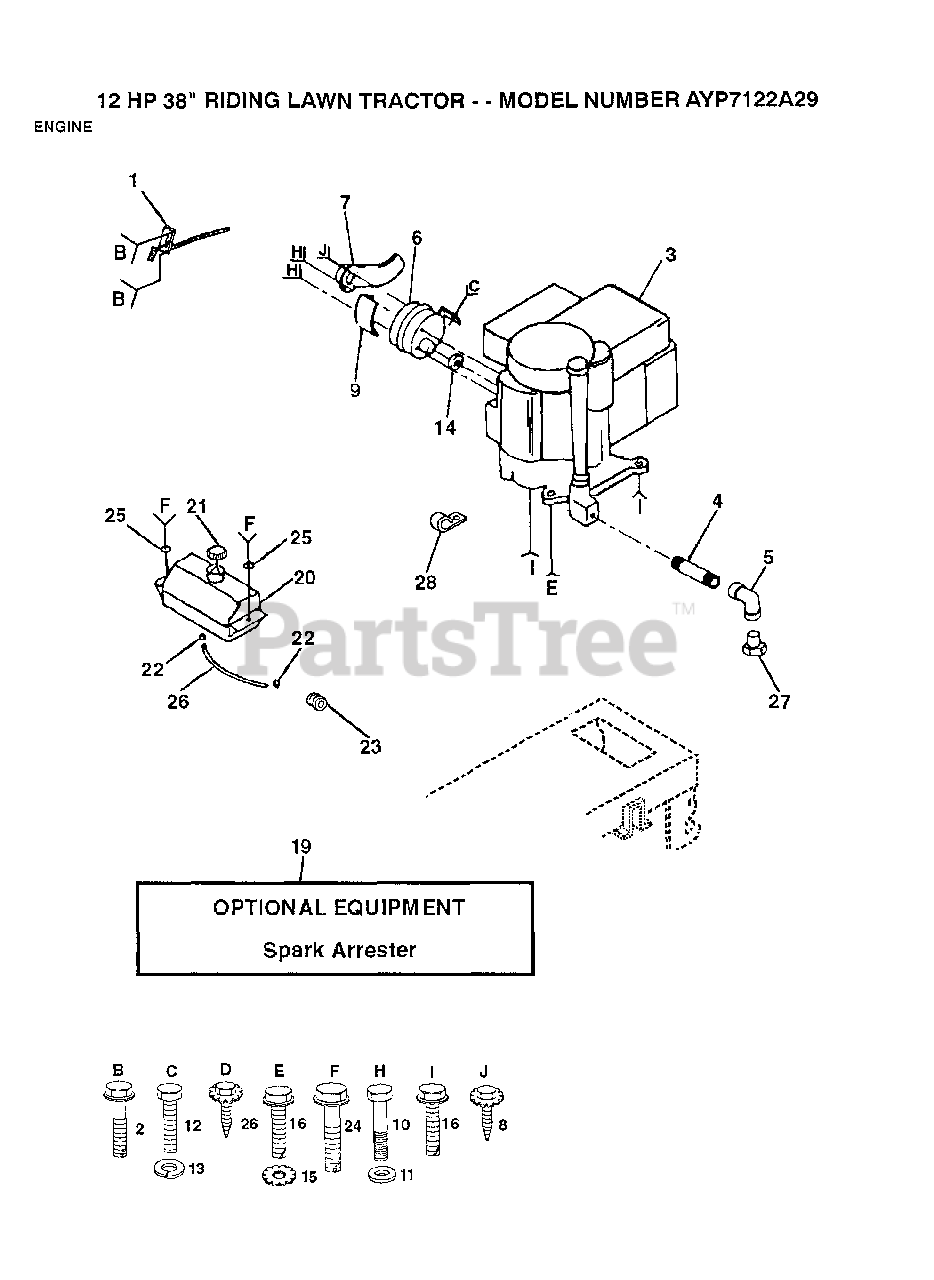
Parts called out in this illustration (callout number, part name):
2	SCREW LT
4	PIPE NIPPLE
5	ELBOW
6	MUFFLER LTV
7	DEFLECTOR MUFFLER
9	SHIELD HEAT LTV
10	"BOLT,HEX"
11	WASHER T
12	BOLT
13	LOCKWASHER
15	LOCKWASHER
16	SCREW
20	TANK.FUEL.LT.
22	HOSE CLAMP
24	SCREW HEX CRT
25	WASHER
26	FUEL LINE T
